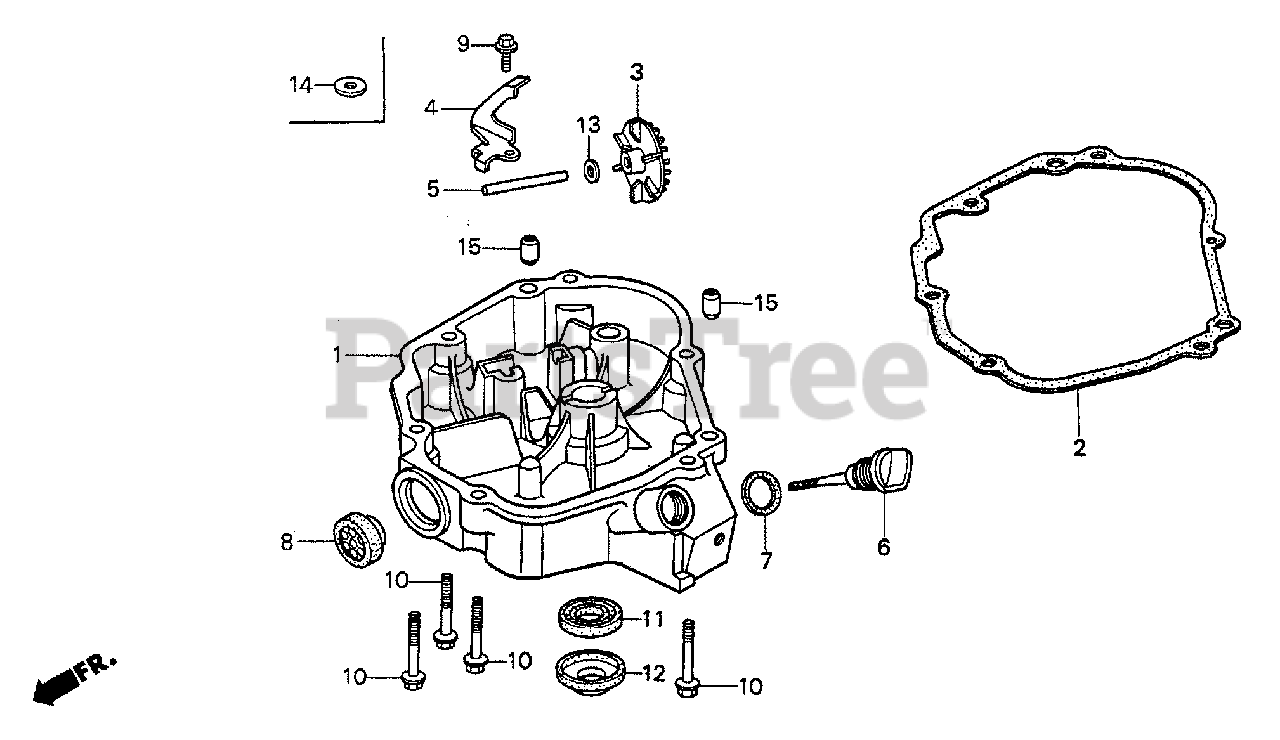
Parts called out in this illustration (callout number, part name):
1	PAN, OIL
2	GASKET, CASE COVER
3	SLINGER, OIL
4	GUIDE, OIL
5	SHAFT, OIL SLINGER
6	CAP, OIL FILLER
7	GASKET, OIL FILLER CAP
8	FINDER, OIL LEVEL
9	BOLT, FLANGE (5X16)
10	BOLT, FLANGE (6X28)
11	OIL SEAL (20X34X6)
12	SEAL, WATER (17X36X5.5)
13	WASHER, PLAIN (6MM)
14	WASHER, PLAIN (5MM)
15	PIN A, DOWEL (8X14)
